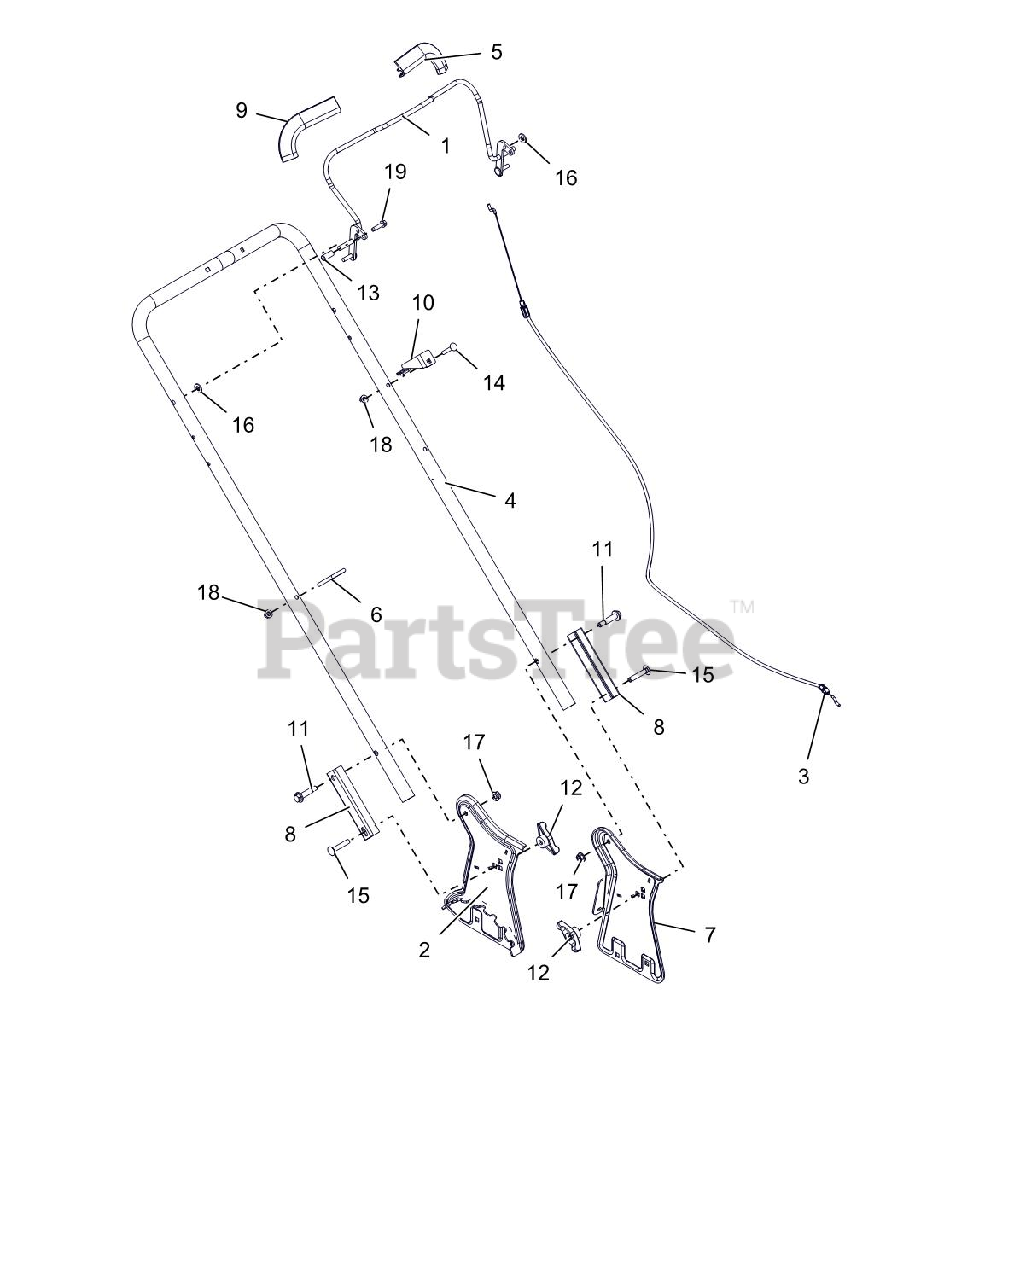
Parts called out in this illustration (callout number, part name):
1	WLDMT, OPC BAIL
2	SUPPORT, RH HANDLBAR
3	CABLE, OPC, RAZOR LM
4	HANDLEBAR, LM
5	GUARD, FINGER - LH
6	HOLDER, RECOIL CORD
7	SUPPORT, LH HANDLEBAR
8	BRKT, HANDLEBAR FIXED ADJUST
9	HAND GRIP W/ DECAL
10	BRKT, CABLE ANCHOR - LM PUSH
11	BLT-SHLDR, .50X1.15X.312-18GR5
12	KNOB,WING .31-18 UNC NYL/TALC
13	CAP, VINYL, .25 ID
14	@BLT-RDHDSQNK .25-20X1.50 G5YZ
15	@BLT-RDHDSQNK .31-18X1.75 G5YZ
16	@WSHR-FL-STL.344X.688X.065YWZC
17	@NUT-LK-TOP-FLG .31-18 YWZC
18	@NUT-LK-TOP-FLG .25-20 YWZC
19	@SCR-TAP .25-20X1.00 HWH TR YZ
